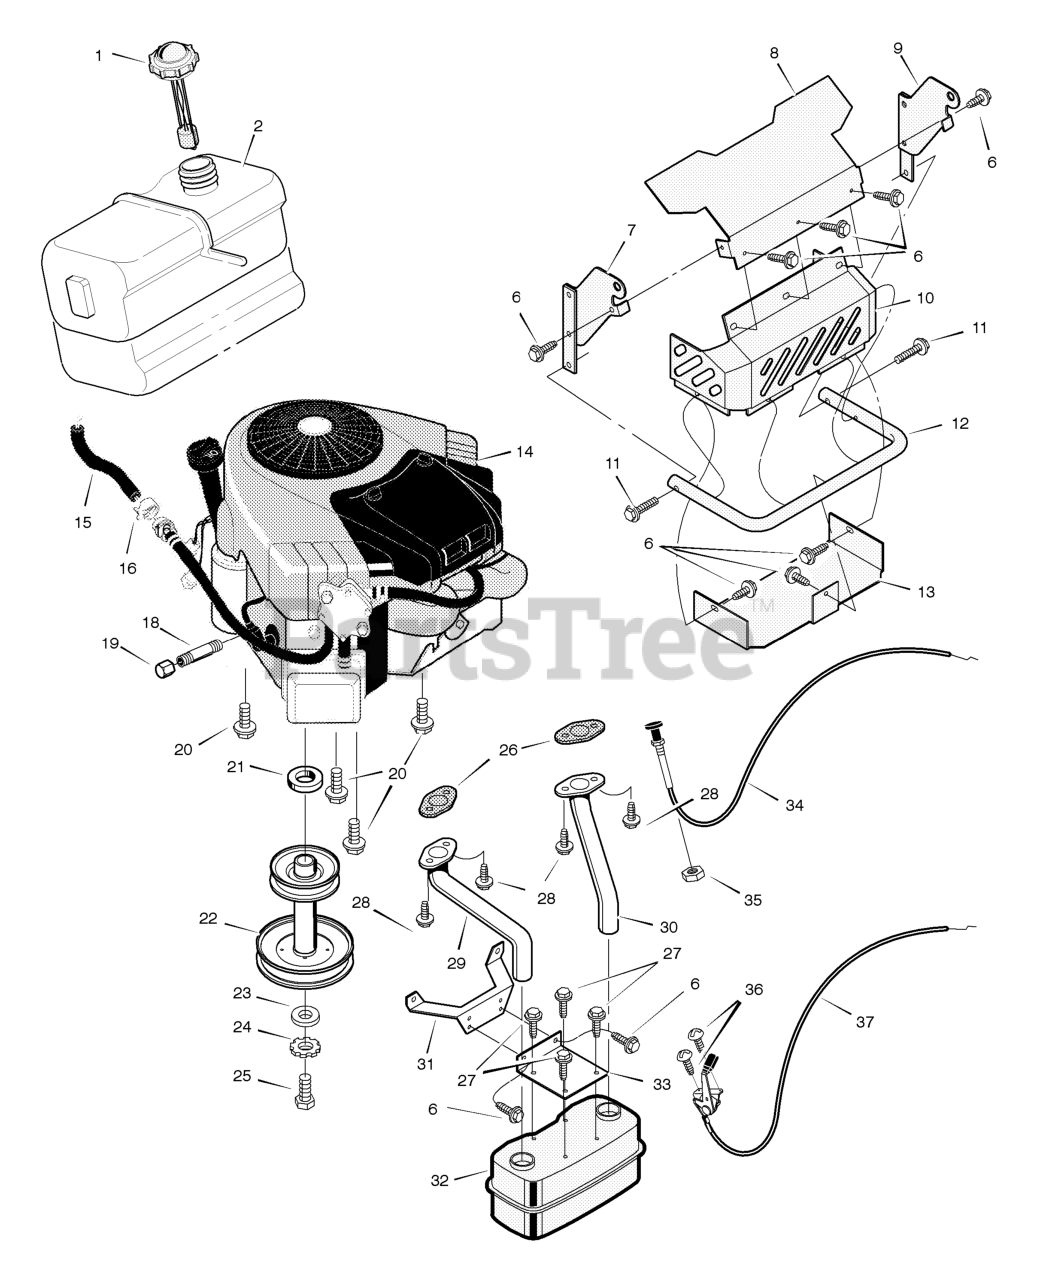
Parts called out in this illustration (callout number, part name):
1	Cap, Fuel with Gauge
2	Tank, Fuel
7	Assembly, Right Grille Support
8	Shield, Heat
9	Assembly, Left Grille Support
10	Shield, Heat
13	Shield, Lower
14	Engine *
15	Fuel Line (Must cut to length)
16	Clamp
18	Pipe, Oil Drain
19	Cap, Oil Drain
20	Bolt
22	Pulley, Stack
24	Lockwasher
29	Tube, Right Exhaust
30	Tube, Left Exhaust
31	Bracket, Muffler Mount
33	Bracket, Muffler
35	Nut
37	Control, Throttle
